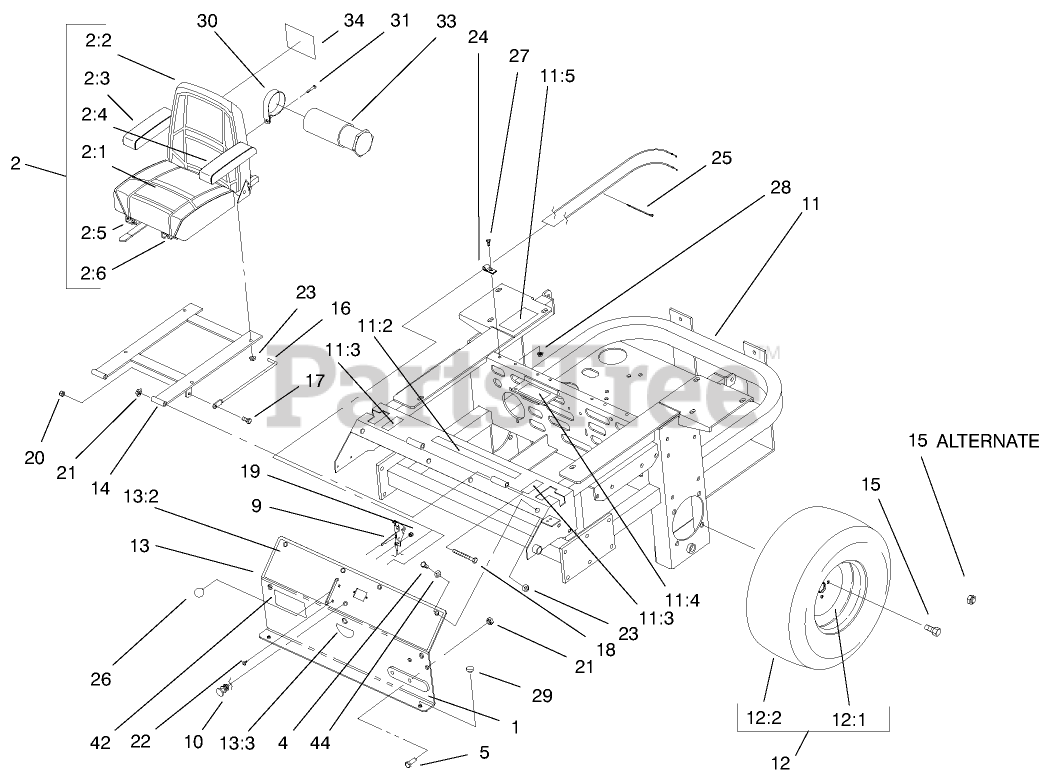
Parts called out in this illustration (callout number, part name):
1	Stop-Park Brake
2	SERVICE ASSEMBLY - SEAT
2	Seat ASM
2:1	Cushion
2:2	Cushion
2:3	Armrest
2:4	Armrest
2:5	Spacer-Track
2:6	Track-Locking, 4"
4	SCREW-HH
5	SCREW-HH
9	Cable
10	Cable-Choke
11	FRAME ASM
11:2	Decal-Battery
11:3	Decal-Motion Control
11:4	Decal-Drive Release
11:5	Decal-Belt Pump
12	Wheel & Tire ASM
12:1	Wheel
12:2	Tire
13	CONSOLE ASM
13:2	DECAL-CONTROL PANEL
13:3	Decal-Fuel Valve
14	Frame-Seat
15	Nut
15	Wheel Bolt
16	Rod-Seat Holdup
17	SCREW-HH
18	SCREW-HH
19	Nut
20	NUT-LOCK NI
21	NUT-HEX
22	Bolt-CARR
23	NUT-HF
24	Clip
25	Tie-Plastic
26	Knob
27	SCREW-HH
28	NUT-HF
29	Bumper
30	CLAMP-R
31	Screw
33	TUBE-MANUAL
34	DECAL
42	Decal-Z255
44	WASHER-PLAIN
